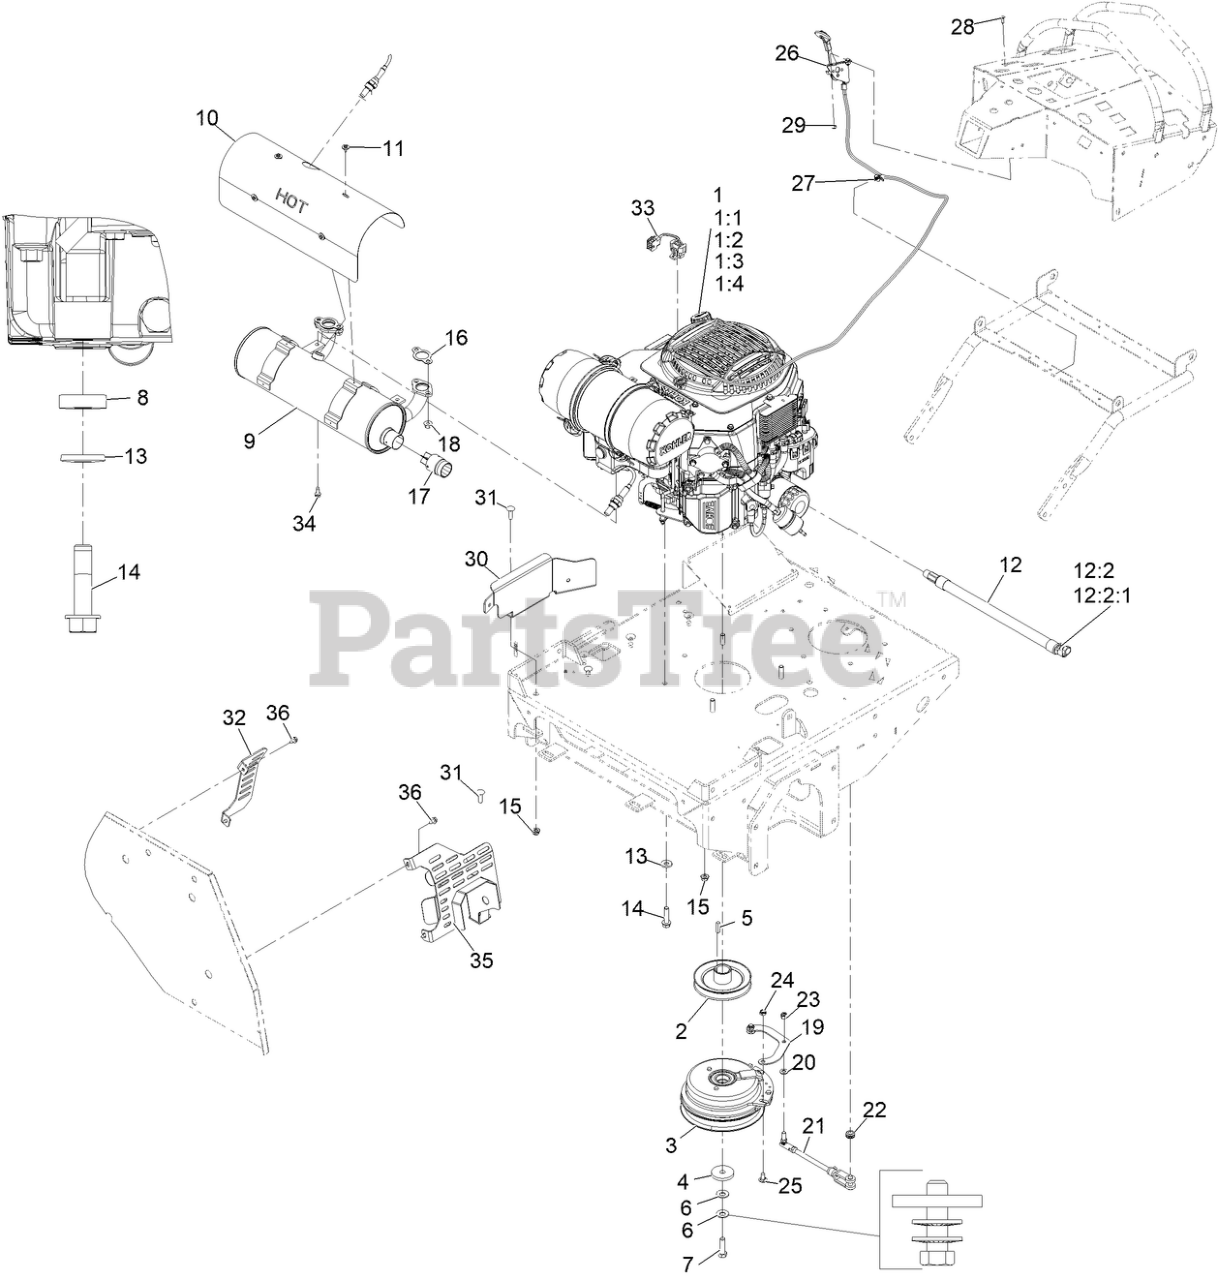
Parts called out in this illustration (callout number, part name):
1	Engine-Kohler Ecv749-3064
1:1	Kohler 52 050 02-S Engine Oil Filter
1:2	Kohler 25 083 01-S Engine Air Filter
1:3	Kohler 25 083 04-S Safety Filter
1:4	Kohler 25 050 42-S Fuel Filter
2	PULLEY-ENGINE
3	CLUTCH-200CMS
4	WASHER-CLUTCH
6	WASHER-SPRING
7	BOLT-HEX, TAP
9	MUFFLER-TTX, EFI
10	SHIELD-MUFFLER,TTX EFI
11	SCREW-HH, THREAD FORMING
12	OIL DRAIN HOSE ASM
12:2	PLUG-HH
12:2:1	O-RING
13	WASHER-BELLEVILLE
14	SCREW-HWH
15	NUT-HF, NI
16	GASKET-EXHAUST
17	Screen-Spark Arrestor
18	NUT-FLANGE
19	STRAP, CLUTCH
20	WASHER-PLAIN
21	ASM, CLUTCH ANCHOR
22	GROMMET
23	NUT-LOCK
24	NUT-LOCK, NI
25	SCREW-CARR
26	CONTROL-THROTTLE
27	CLIP-TIE, FIR TREE W/TIE, 5MM/.196"" HOLE
28	BOLT-CARR
29	NUT-LOCK, NI
30	GUARD, HEAT
31	SCREW-CARR
32	Guard, Heat [black]
33	HARNESS-ENGINE JUMPER
34	SCREW-HWHTF
35	Weld, Muffler Guard [black]
36	SCREW-HWHTF
